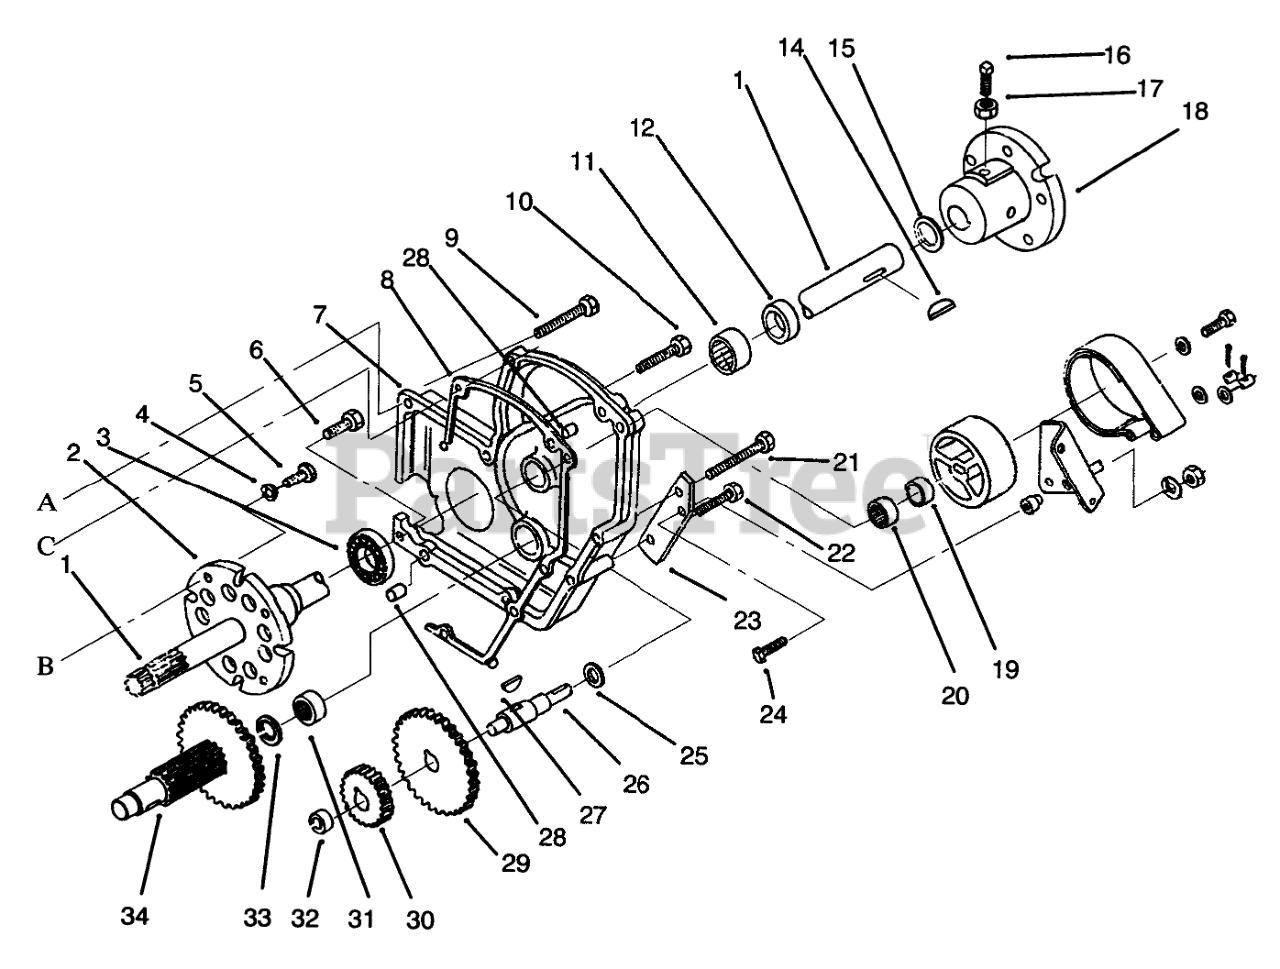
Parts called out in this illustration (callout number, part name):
1	AXLE-REAR LH
2	END CAP-DIFFERENTIAL
3	BEARING-BALL
4	WASHER
5	BOLT-HEX
7	CASE TRANS LH
8	GASKET-TRANSMISSION
9	SCREW-HH
11	BEARING
12	SEAL-OIL
14	KEY-WOODRUFF
15	WASHER-THRUST
16	SCREW-SET, SQH
17	WASHER-THRUST
18	Hub Rear
19	Seal
20	NEEDLE BEARING
21	SCREW-HH
22	SCREW-HH
23	BRACKET-BRAKEB
24	SCREW-HH
25	Race Thrust
26	SHAFT GEAR
27	Key
28	PIN-LOCATING
29	GEAR 46 TEETH
30	GEAR 20 TEETH
31	BEARING-NEEDLE
32	BEARING-NEEDLE
33	WASHER-THRUST
34	ASSY GEAR
